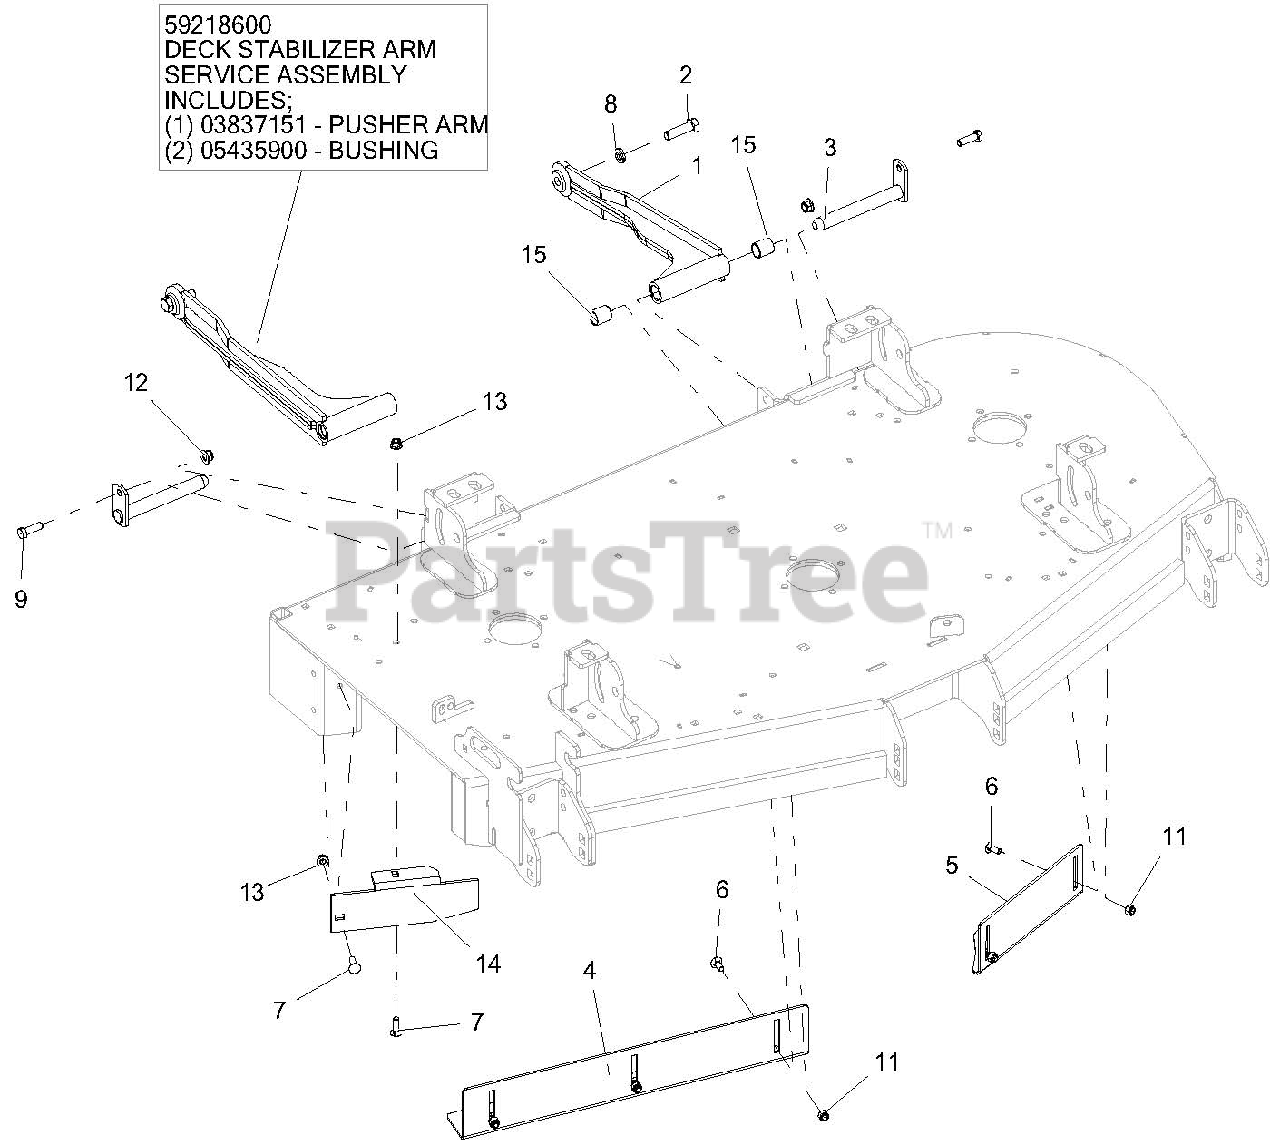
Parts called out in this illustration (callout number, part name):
1	WMT, DECK STABILIZER ARM-BLACK
1	DECK STABILIZER ARM SERVICE ASSEMBLY
1	PUSHER ARM
1	BUSING
2	BLT-HEX .50-13X1.75 GR5 YWZC EP80
3	WLDMT, MOWER MTG. PIN
4	BAFFLE, 52" RH VACUUM-BLACK
5	BAFFLE, 52" LH VACUUM-BLACK
6	BLT-RDHDSQNK .31-18X.75 G5 YWZC
7	BLT-RDHDSQSHNK .31-18X1.00 G5Y
8	WSHR-LK .50X.125 REG YWZC
9	BLT-HEX .38-16X1.25 GR5 YWZC
11	NUT-LK-NYL .312-18 YWZC
12	NUT-LK-NYL-FLG .38-16 YWZC
13	NUT-LK-NYL-FLG .31-18 YWZC
14	BAFFLE, 52" DISCHARGE-RED
15	BRG, .750 X .875 X 1.000
